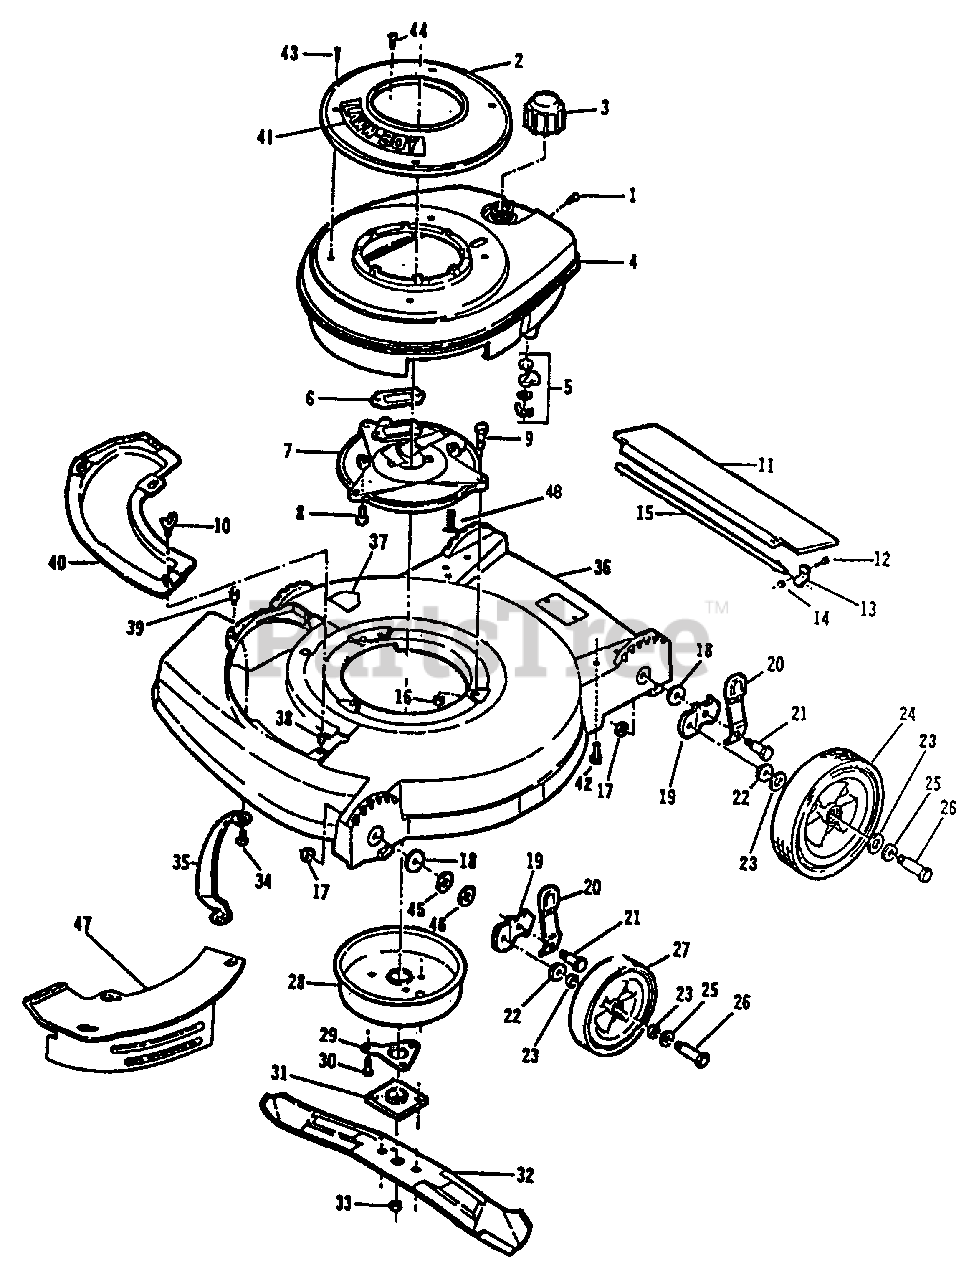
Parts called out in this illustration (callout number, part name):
1	Screw
2	Starter Base and Nut Assembly
3	Fuel Cap
4	Shroud-Engine
5	Fuel Shut-Off Assembly
6	Gasket-Exhaust
7	Plate-Muffler
8	Screw-Muffler Plate to Block
9	Screw-Muffler Plate to Housing
10	Wing Screw
11	Shield-Trailing
12	Screw
13	Clamp
14	Nut
15	Rod-Trailing Shield
16	Nut-Muffler Plate to Housing
17	Nut-Wheel Height Adjust
18	Washer-Wheel Height Adjust
19	Bracket-Wheel Height Adjust
20	Knob and Spring Assembly
21	Bolt-Shoulder
22	Washer
23	Washer-Felt
24	Wheel-Rear
25	Washer-Wheel Bolt
26	Bolt-Wheel
27	Wheel-Front
28	Muffler Cover Assembly
29	Support-Crankshaft
30	Screw-Muffler to Muffler Plate
31	Collar and Plate Assembly
32	Blade-21"
33	Nut
34	Screw
35	Toe Bar
36	Housing Assembly
37	Decal-Blade Contact Warning
38	Grommet
39	Screw-Plate Mounting
40	Cover Plate
41	Applique-Starter Base
42	Screw-Handle Bracket to Hsg.
43	Screw-Shroud
44	Screw-Starter Mounting
45	Washer-Shim
46	Washer-Shim
47	Mulcher Plate Kit w/ Decal
48	Screw-Muffler Plate To Block
